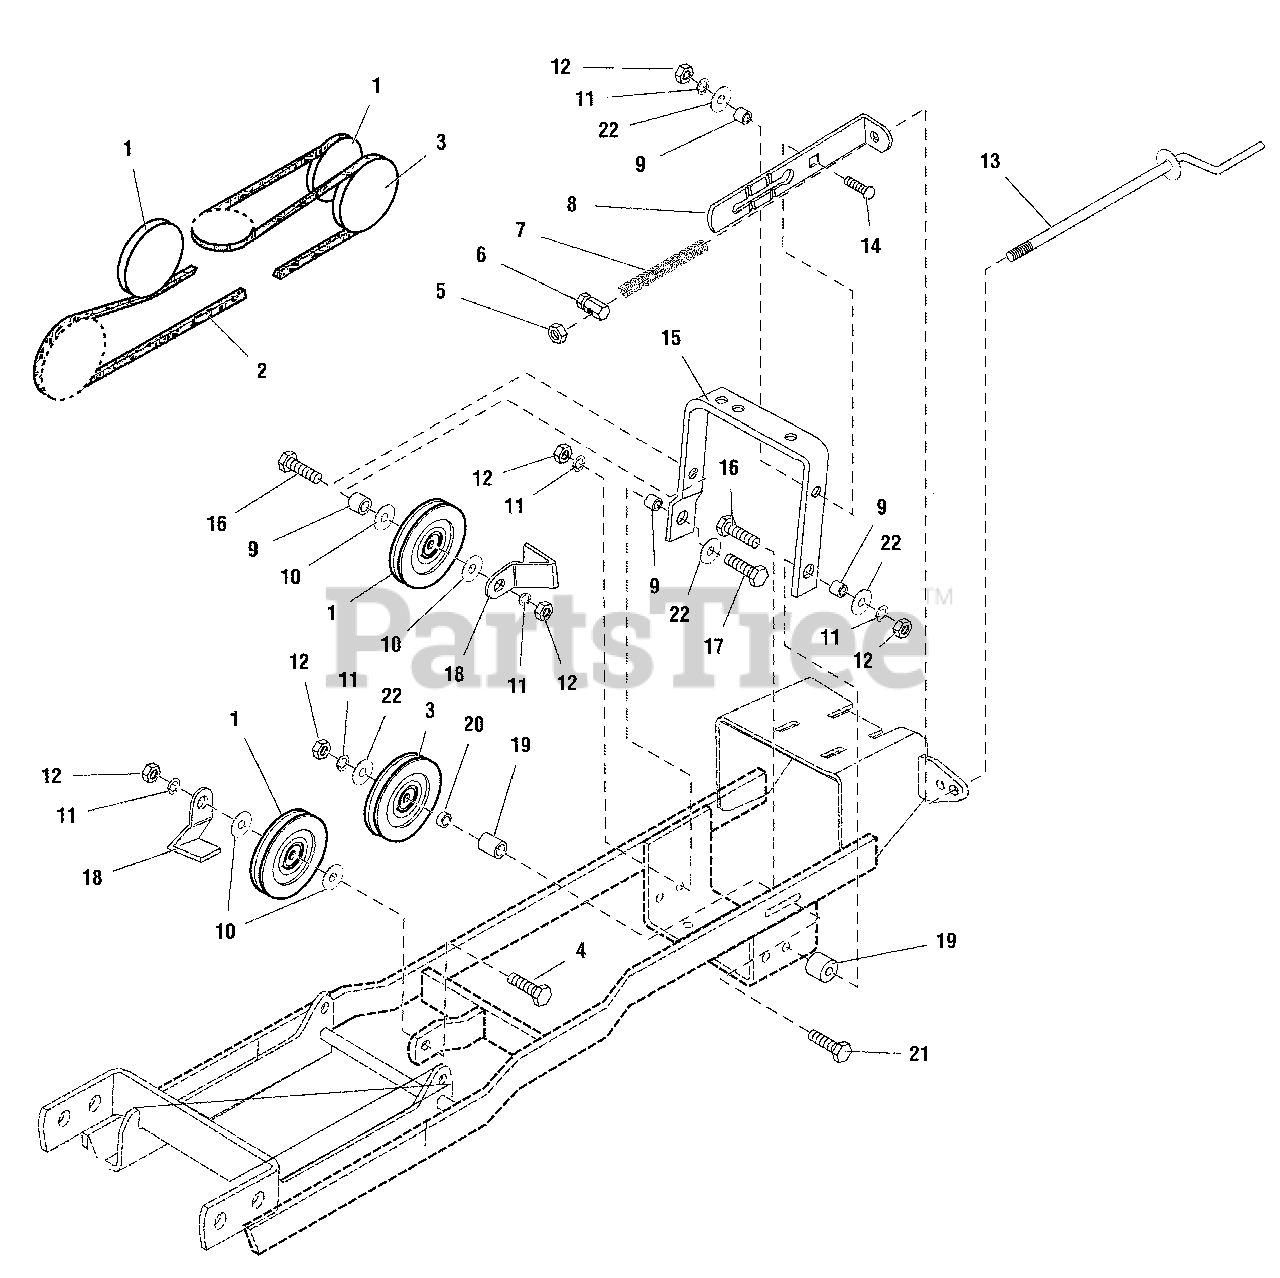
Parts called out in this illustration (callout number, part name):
1	PULLEY, Flat
3	PULLEY ASSEMBLY
4	CAPSCREW, Hex Head, 3/8-16 x 3/4
5	NUT, Hex Lock, 3/8-16
8	GUIDE ASSEMBLY, Spring
10	WASHER, 3/8 x 1 x 1/8
11	LOCKWASHER, 3/8
12	NUT Hex, 3/8-16
13	ROD ASSEMBLY
14	CARRIAGE BOLT, 3/8-16 x 1-1/4
15	PIVOT BRACKET
16	CAPSCREW, Hex Head, 3/8-16 x 2
17	CAPSCREW, Hex Head, 3/8-16 x 1-1/4
18	BELT GUIDE
21	CAPSCREW, Hex Head Whiz Lock, 3/8-16 x 2-3/4
22	WASHER, 3/8
